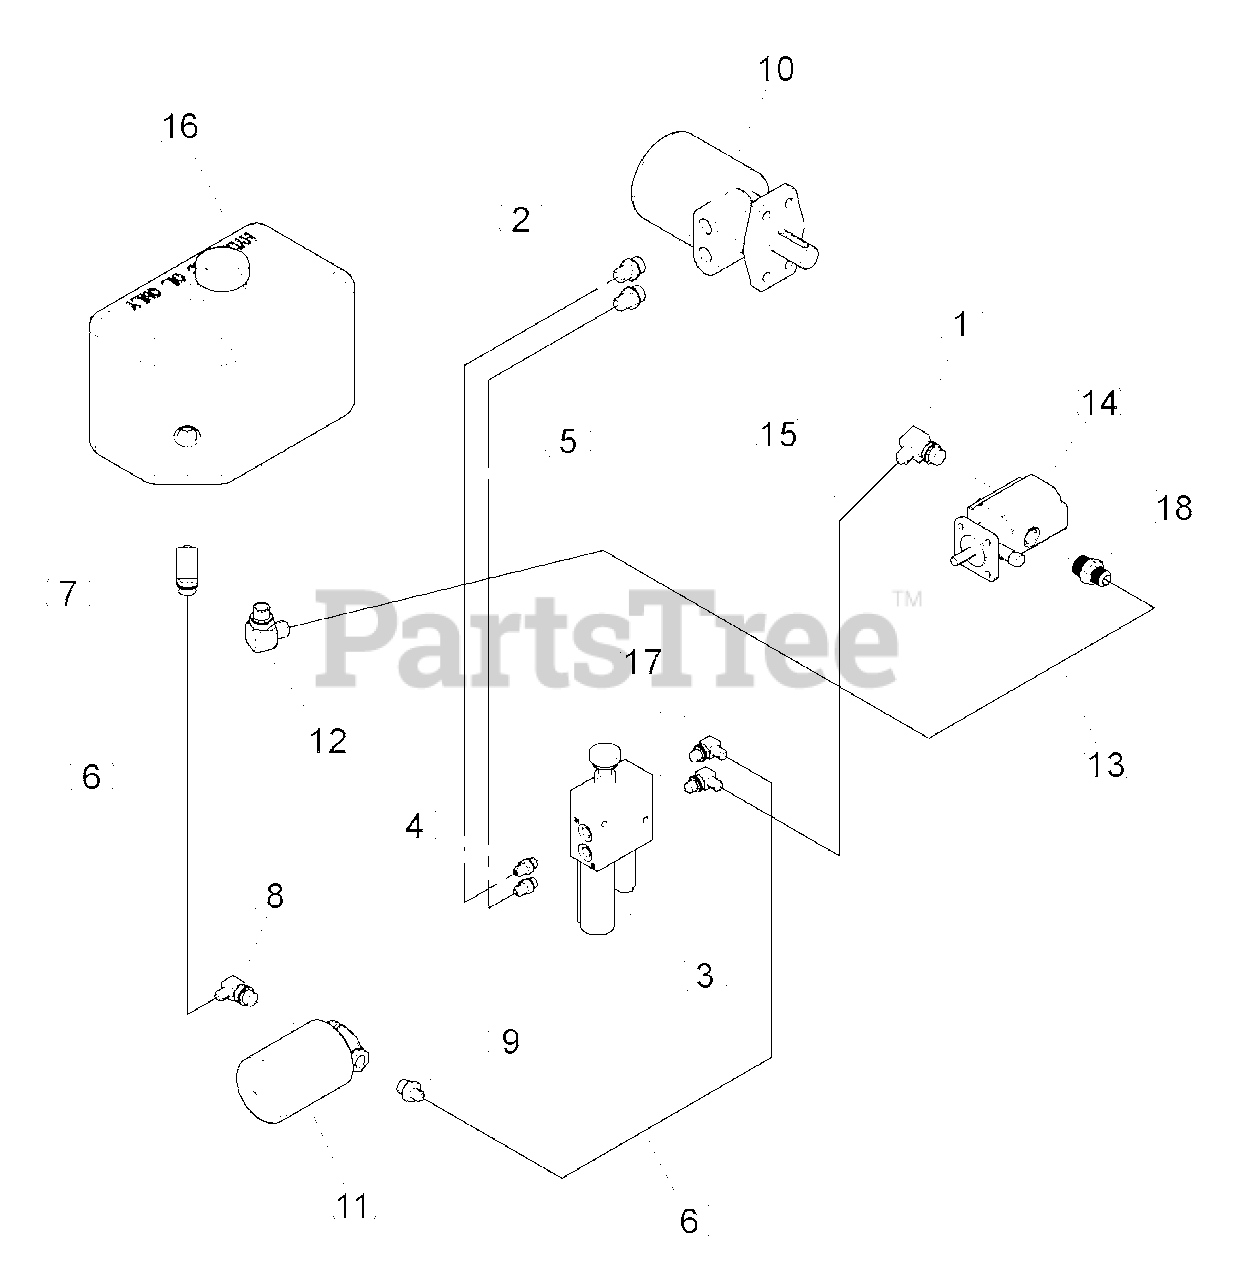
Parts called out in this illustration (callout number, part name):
1	ADAPTER, -10MORING/-8MJIC 90 DEG
2	ADAPTER, -10MORING/-8MJIC
3	VALVE, HYDRAULIC CONTROL
4	ADAPTER, -6MORING/-6MJIC
5	HOSE ASSEMBLY, -8FMJ/-6FMJ X 31
6	HOSE ASSEMBLY, -6FMJ/-6FMJ X 30
7	ADAPTER, -10MORING/-6MJIC 90
8	ADAPTER, -8MORING/-6MJIC 90 DEG
9	ADAPTER, -8MORING/-6MJIC
10	MOTOR, 45 CU IN HYDRAULIC
11	ASSEMBLY, HYDRAULIC FILTER
12	ADAPTER, -10MORING/-10MJIC 90 DEG
13	HOSE ASSEMBLY, -10FMJSW90/-10FMJ X 42
14	PUMP, 2 STAGE CW HI/LO 0.605 DISP.
15	HOSE, -8 FMJ/-6FMJ X 31" HYDRAULIC
16	TANK, HYDRAULIC
17	ADAPTER, -6MORING/-6MJIC 90 DEG
18	ADAPTER, HYDRAULIC PUMP FITTING
